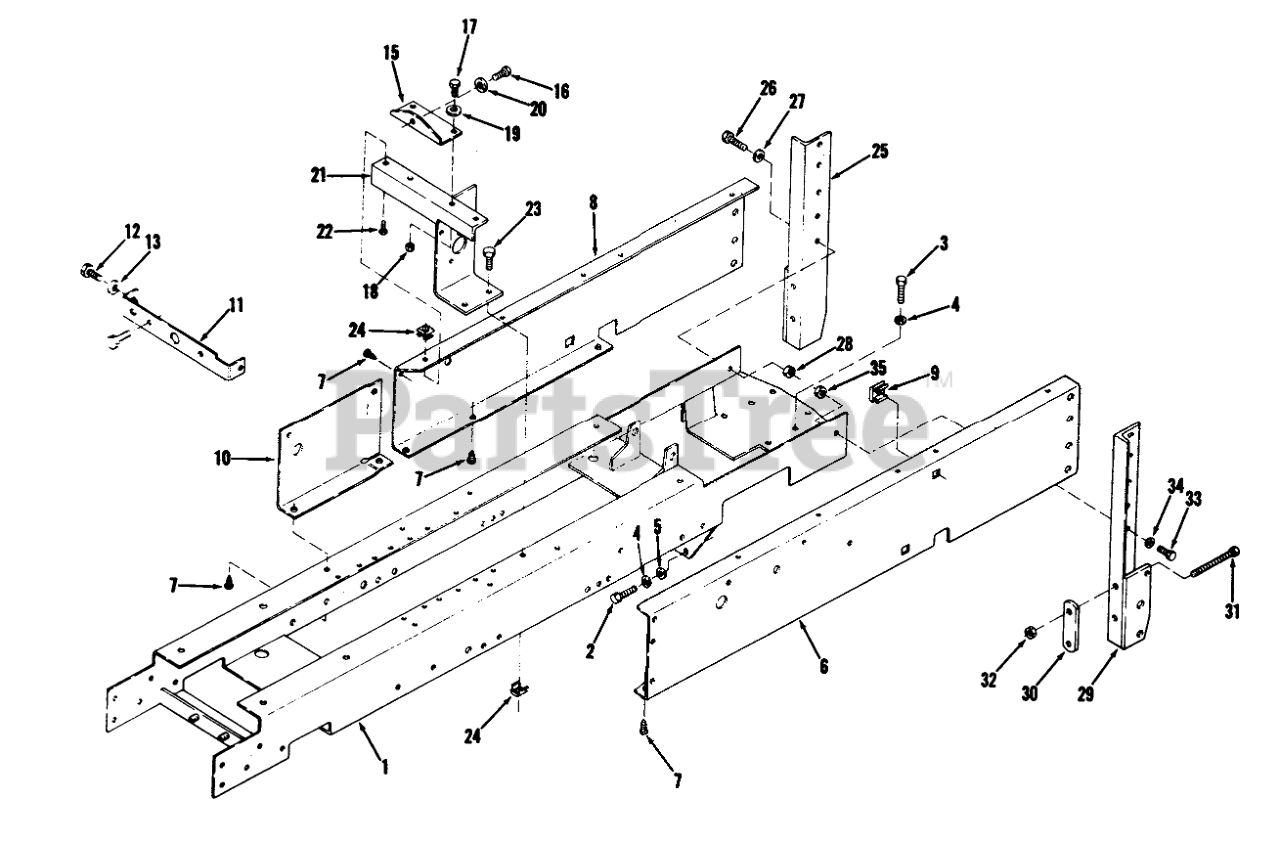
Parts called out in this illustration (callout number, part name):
1	Assy-Frame
2	Bolt
3	BOLT
4	LOCKWASHER
5	Washer
6	Side Panel, L.H.
7	Bolt
8	Hex Nut
9	Nut-Tinnerman
10	Access Plate
11	Pump Mounting Plate
12	SCREW
13	WASHER 5/16 SAE
15	Pump Hanger Bracket
16	Bolt
17	HHCS
18	Nut
19	WASHER 5/16 SAE
20	LOCKWASHER
21	Steering Gear Support
22	Bolt
23	BOLT
24	NUT
25	Assy-Angle RH
26	BOLT
27	Washer
28	NUT
29	Assy-Angle LH
30	BRACKET-REAR LINK MOUNTING
31	HHCS
32	NUT
33	BOLT
34	Washer
35	Nut
